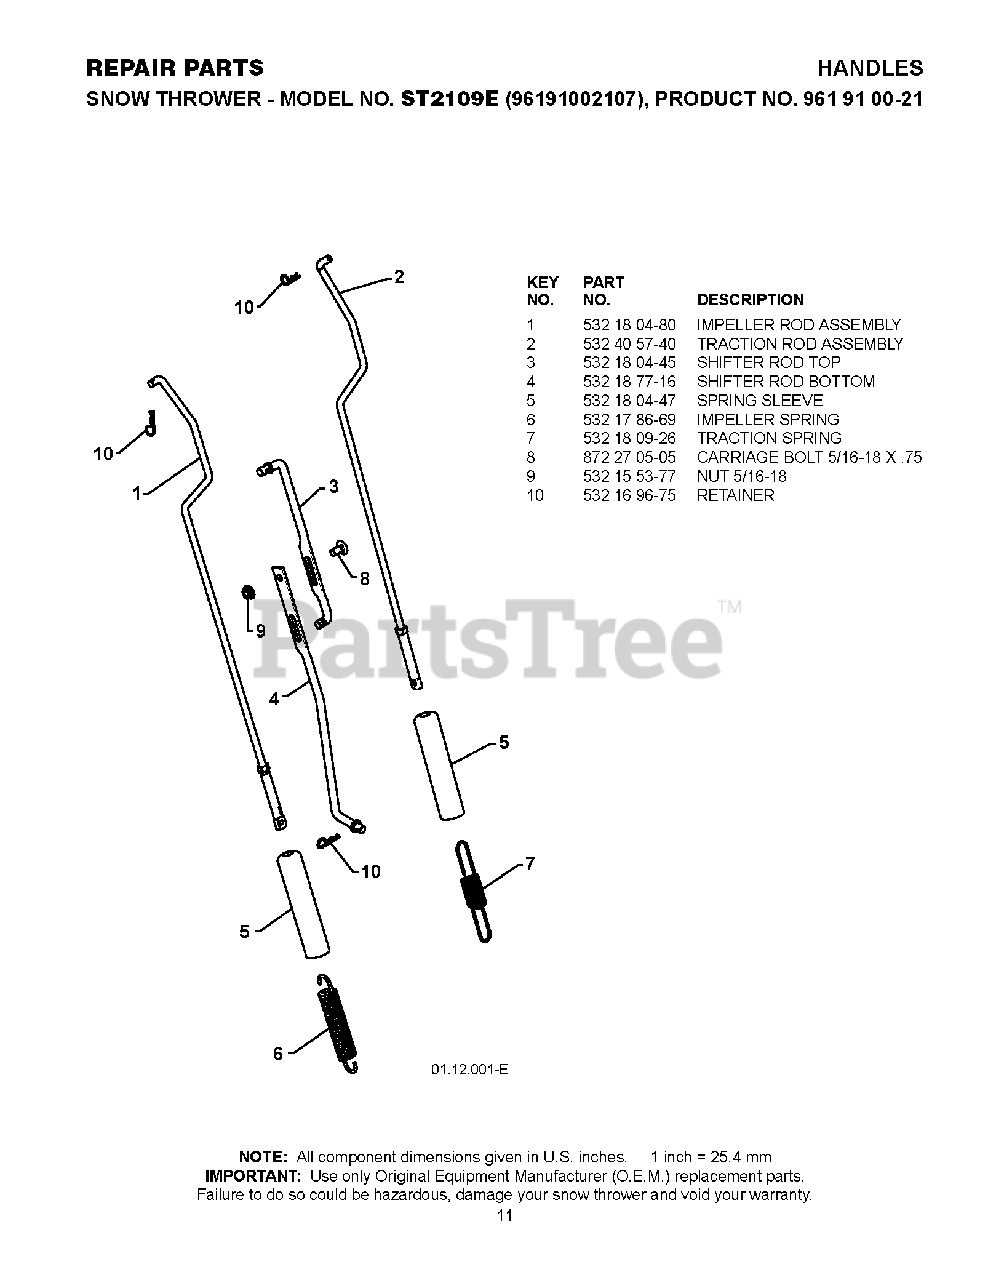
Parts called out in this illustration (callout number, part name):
1	ROD.ASM.IMPELLER
2	ROD.ASM.TRACTION
3	ROD, UPPER SPEED CONTROL
4	ROD, LOWER SPEED CONTROL
5	SLEEVE, SPRING
6	SPRING, AUGER CONTROL
7	SPRING, TRACTION DRIVE
8	BOLT
9	NUT.FLANGE.5/16
10	SPRING RETAINER
